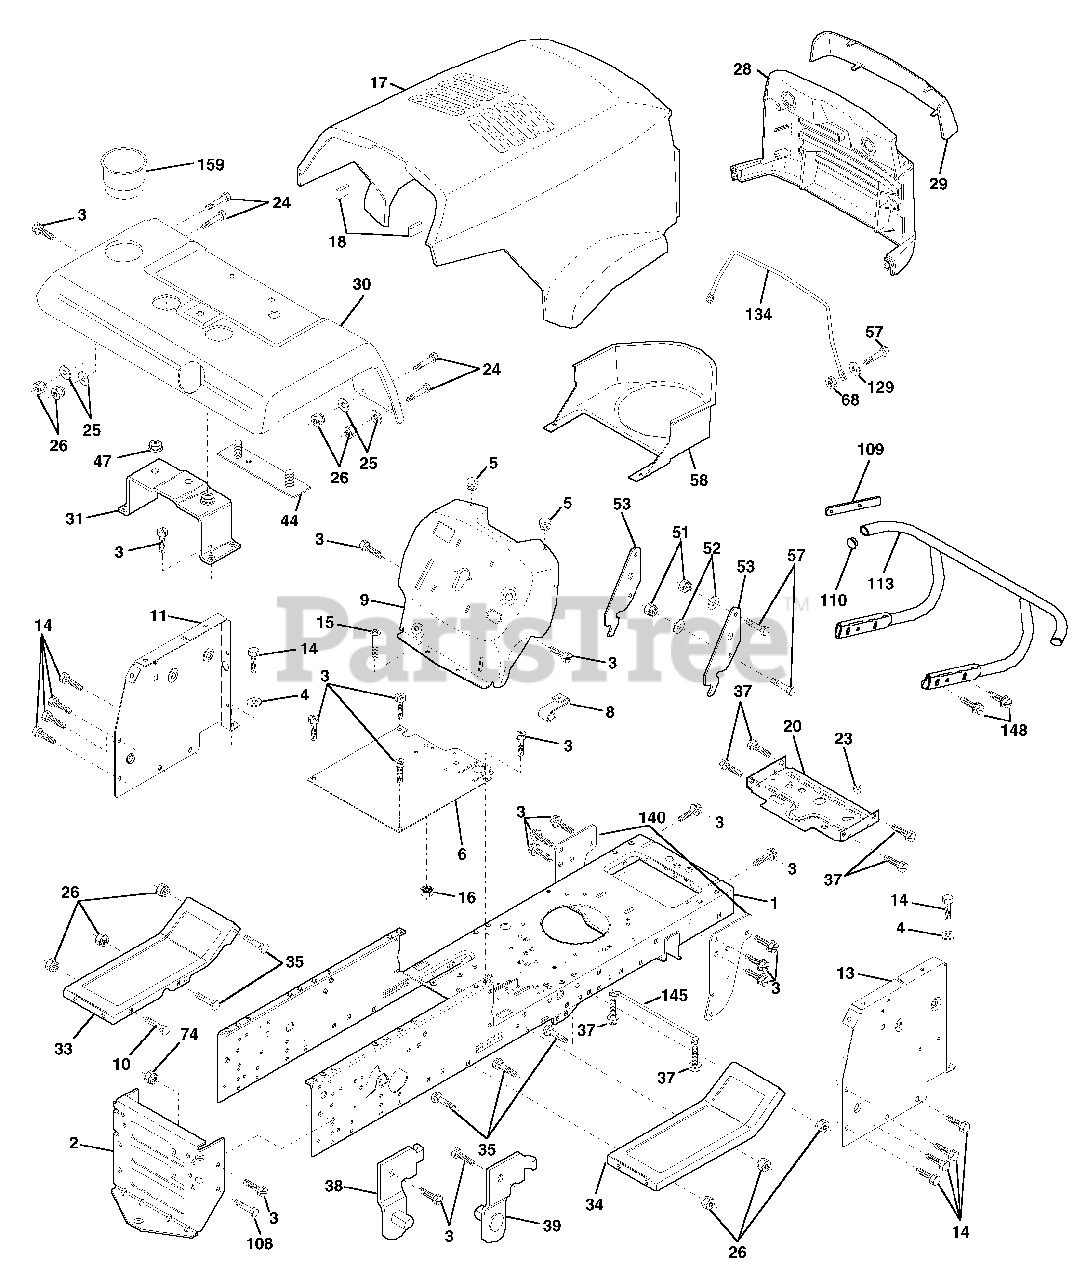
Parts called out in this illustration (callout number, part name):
1	Chassis Weldment
2	Drawbar
3	Screw Thdrol 3/8-16x3/4 Ty-tt
4	Washer 13/32 x 3/4 x 16 Ja.
8	Clip Insulator
9	Dashboard
10	Bolt
11	Panel Asm.
13	Panel Asm.
14	Screw 3/8-16 x 1/2 Ty-Tt
15	Screw 5/16-18 Unc x 3/4
16	Nut Keps 5/16-18 Unc
17	Hood
20	Plate Mtg Battery/Fuel Tank
24	Bolt 3/8-16 Unc x 1 Gr. 5
25	Washer 13/32 x 13/16 x 12 Ga.
26	Nut Lock w/Insert 3/8-16 UNC
28	Grille
29	Grille Lens
31	Bracket
33	Foot Rest, L.H.
34	Foot Rest, R.H.
35	Bolt 3/8-16 x 3/4
37	Screw 5/16-18 x 1/2 Tyt
38	Bracket Asm Pivot LH
39	Bracket Asm Pivot RH
44	Strap Asm. Fender
47	Nylon Washer
51	Lock Nut 1/4-20
52	Washer 9/32 x 7/8 x 16 Ga.
53	Bracket LT/PL Husq.
57	Hex Bolt 1/4-20 x .75
58	Duct Intake Air
68	Nut Keps 1/4-20 UNC
74	Nut, Crownlockt 3/8-16 UNC
108	Hex Bolt 3/8-16 UNC x 3.4
109	Bracket Extension Bumper
110	Plug Plastic
113	Bumper Asm.
129	Washer 9/32 x 5/8 x 16 Ga.
134	Rod Support Hood
140	Bracket Suspension Front
145	Rod Pivot Chassis Hood
148	Screw Throl 3/8-16 x 1-1/4
159	Cupholder YTGT Grey
